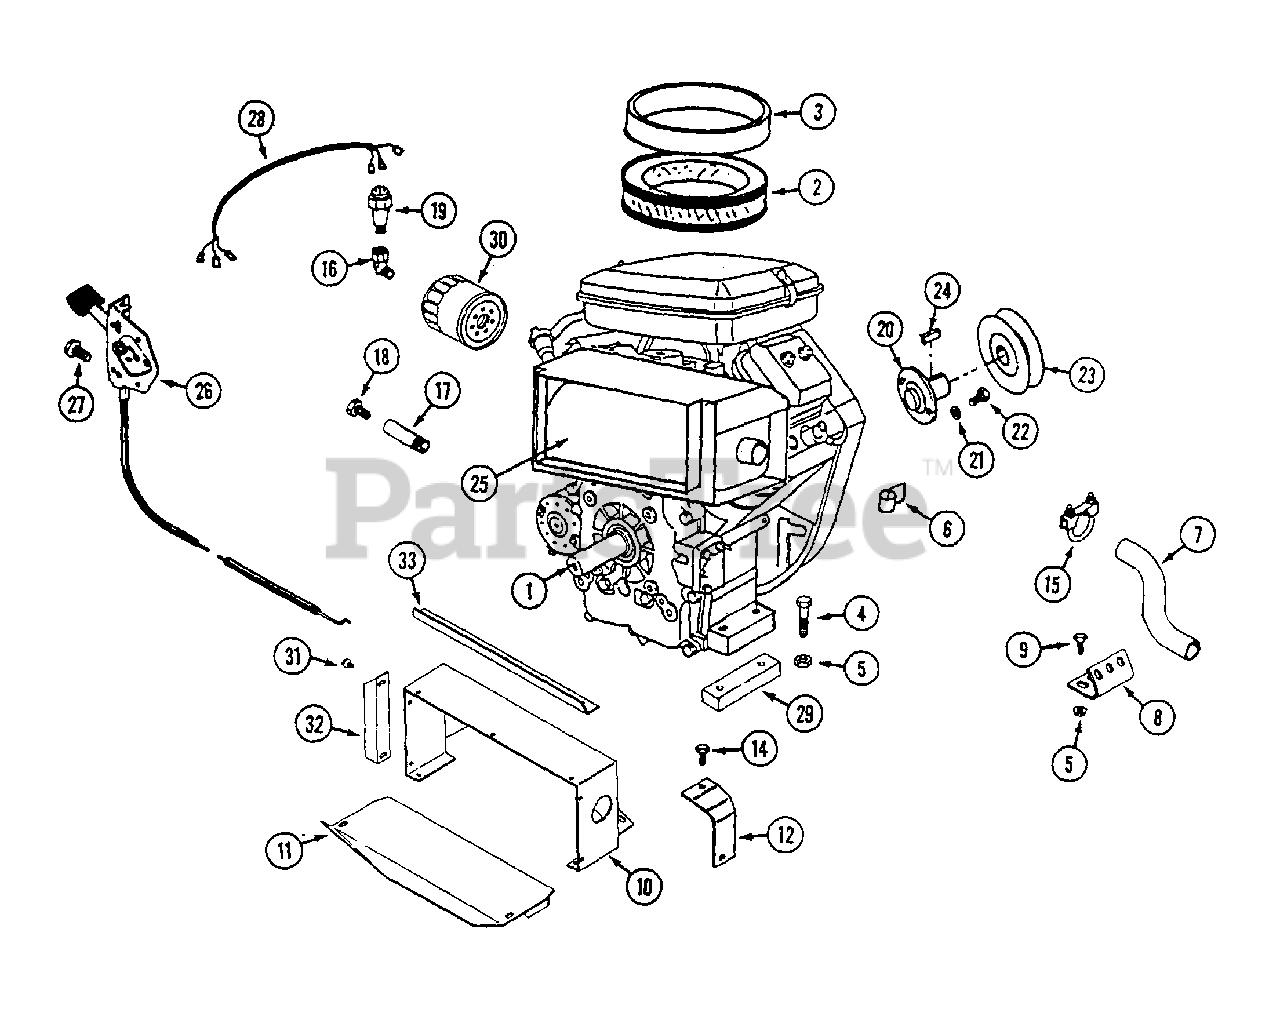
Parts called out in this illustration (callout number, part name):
1	ENGINE - (20 hp)
2	ELEMENT - air cleaner
3	PRE-CLEANER
4	BOLT - 5/16" - 18 X 2-3/4"
5	NUT - 5/16" - 18
6	CLIP - "J"
7	PIPE - exhaust
8	BRACKET - exhaust pipe
9	BOLT - 5/16" - 18 x 1"
10	DUCT - muffler, upper
11	DUCT - muffler, lower
11	DUCT - bottom
12	SUPPORT - duct
14	SCREW - M6 x 10
15	CLAMP - exhaust
16	FITTING - street elbow, 1/8" - 27 NPT 90°.
17	NIPPLE - pipe 3.5"
18	PLUG - 1/2" - 20
19	UNIT - oil sending
21	LOCKWASHER - 3/8"
22	BOLT - 3/8" - 16 x 1"
23	PULLEY - engine
24	KEY - 1/4" x 1/4" x 1"
25	MUFFLER
26	CABLE - choke
26	CABLE - throttle
27	SCREW - #12 X 1/2"
28	HARNESS - wire
29	SPACER - engine mount
30	FILTER - oil
31	SCREW - #8 - 18 x 3/4"
32	BRACKET - angle (short)
33	BRACKET - angle (long)
